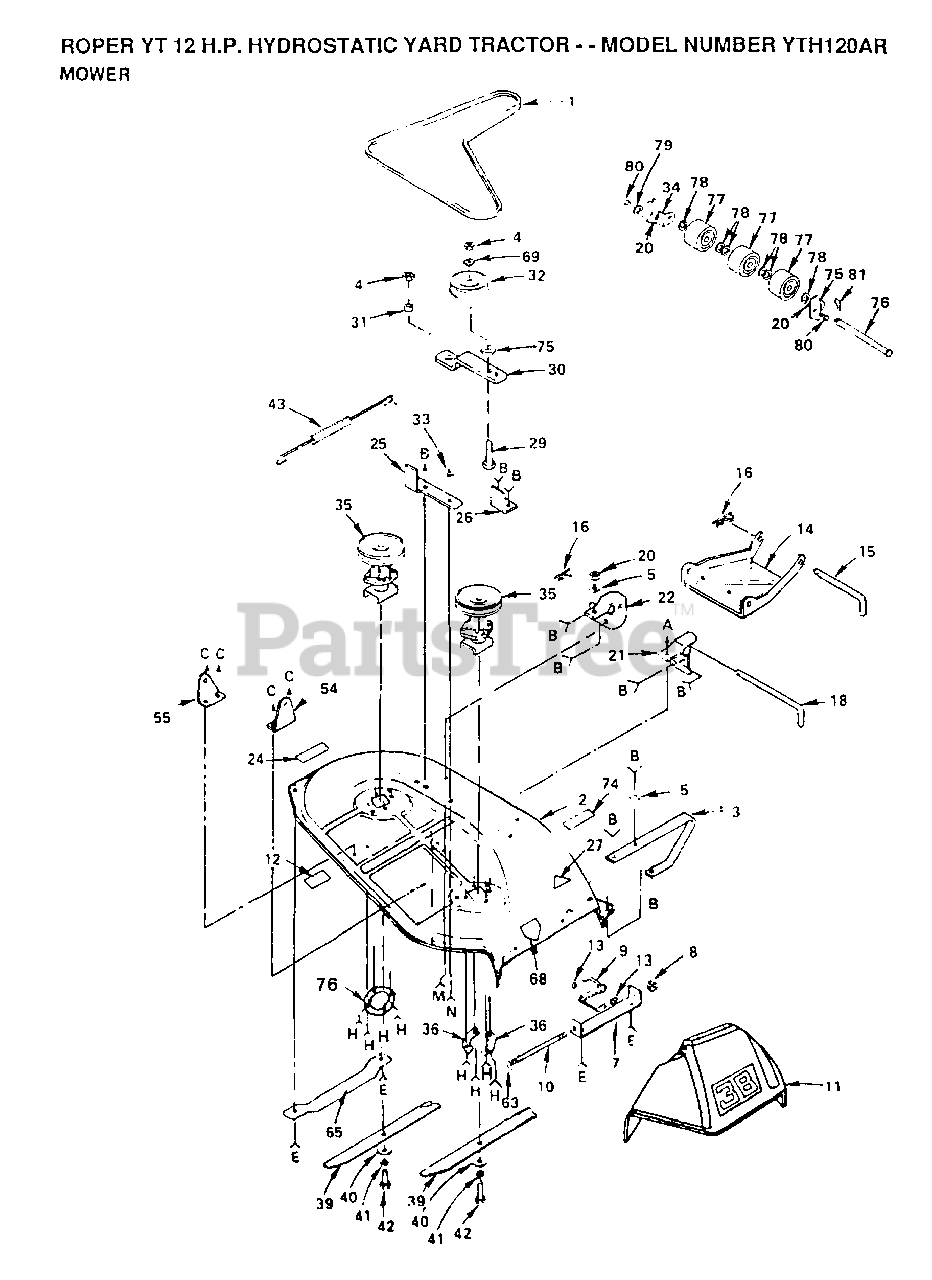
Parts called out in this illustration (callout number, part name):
1	BELT-V.79.1.MWR
5	WASHER M
6	BOLT
8	NUT PUSH M
11	DEFLECTOR-SHLD T
13	CAP-SLEEVE LT
14	LINK.PARALLEL
15	"ROD, FRT. PARAL T"
16	SPRING.RETAINER
18	HINGE PIN T
21	BRACKET RH LT
22	BRACKET LH T
24	DECAL YT
25	SUPPORT ARM T
26	STOP T
31	SPACER RETAINER
32	PULLEY IDLER
33	"WASHER, WEAR LT"
35	"JACKSHAFT.38""LT"
36	SUPPORT PLATE LT
39	"BLADE.38"" HI-LI"
40	WASHER
42	BOLT.3/8-24X1-1/2
43	"SPRING.EXT.8.5"""
54	"BRKT,SUSP RH T"
55	"BRKT,SUSP REAR LH"
63	WASHER
65	RUNNER-LH M
68	DECAL WARNING
69	WASHER
75	WASHER
76	SUPPORT T
77	PIVOT PIN T
78	ROLLER T
79	WASHER T
81	BOLT
